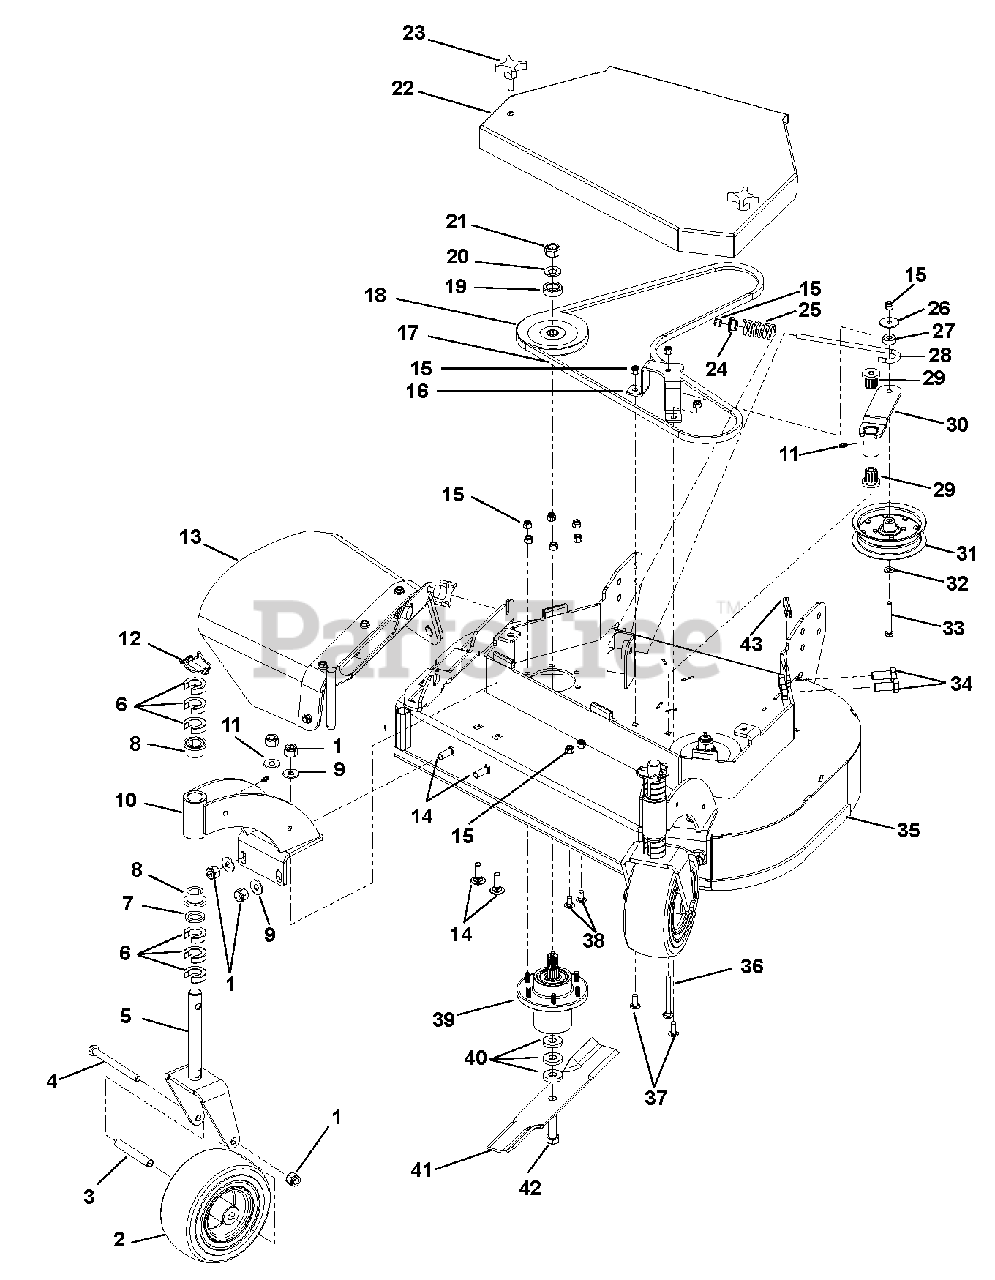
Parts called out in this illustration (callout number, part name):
1	Locknut, .50-13 Nyloc
2	Assembly, Wheel and Tire 9 x 3.5
3	Tube, Caster Axle
4	Bolt, .50-13 x 5.50 Hex Grade 5
5	Weldment, Caster Yoke w/ EverRide Paint
6	C-Spacer, 1.00 x 1.77 x .500
7	Bushing, 1.03 x 1.50 x .179
8	Bearing, Flange 1.00 x 1.25 x 1.00
9	Washer, .438 Regular Flat
10	Weldment, Strut Front FXWLK w/ EverRide Paint
11	Fitting, .25-28 Straight Grease Zerk
12	Pin, LNC .438 x 2.00
13	Discharge Shield Assembly
14	Bolt, Round Head Square Neck .50-13 x 1.50 Grade 5
15	Locknut, .38-16 Nyloc
16	Bracket, Idler
17	Belt, HB 80.3 Elbow AMD OHR
18	Pulley, V-Belt Narrow Spline
19	Spacer, Spindle Top-Pulley 1.500 x 1.000 x .510
20	Washer, .75 x 1.313 x .113
21	Locknut, .75-16 Crown
22	Weldment, Belt Shield 36" GRWK
23	Knob, .375 x 1.25-4 Prong
24	Keeper, Spring
25	Spring, COM 1.22 x .162 x 2.50
26	Washer, Flat .375 x 1.50 x .063
27	Bushing, .380 x 1.00 x .410
28	J-Bolt, .375-16 x 7.88
29	Bearing, Flange M10 x M25 x M27 Fluted
30	Weldment, Idler Arm w/Offset
31	Pulley, Flat 5.0 x .38 w/BRG
32	Washer, .406 x .813 x .065 Flat
33	Bolt, .38-16 x 2.75 Hex Grade 5
34	Bolt, Hex .625-11 x 1.50 Grade 8
35	36" EverRide Gear Deck with Decals
36	Bolt, .375-16 x 3.50 Round Head Square Neck Grade 5
37	Bolt, .375-16 x 1.00 Round Head Square Neck Grade 5
38	Bolt, Round Head Square Neck .38-16 x .75
39	Assembly, Spindle Housing
40	Washer, Blade
41	Blade, 18.000 x .80 Lift
42	Bolt, .625-11 x 2.00 Hex 8
43	Trim, 1/4" Trim-LOK
